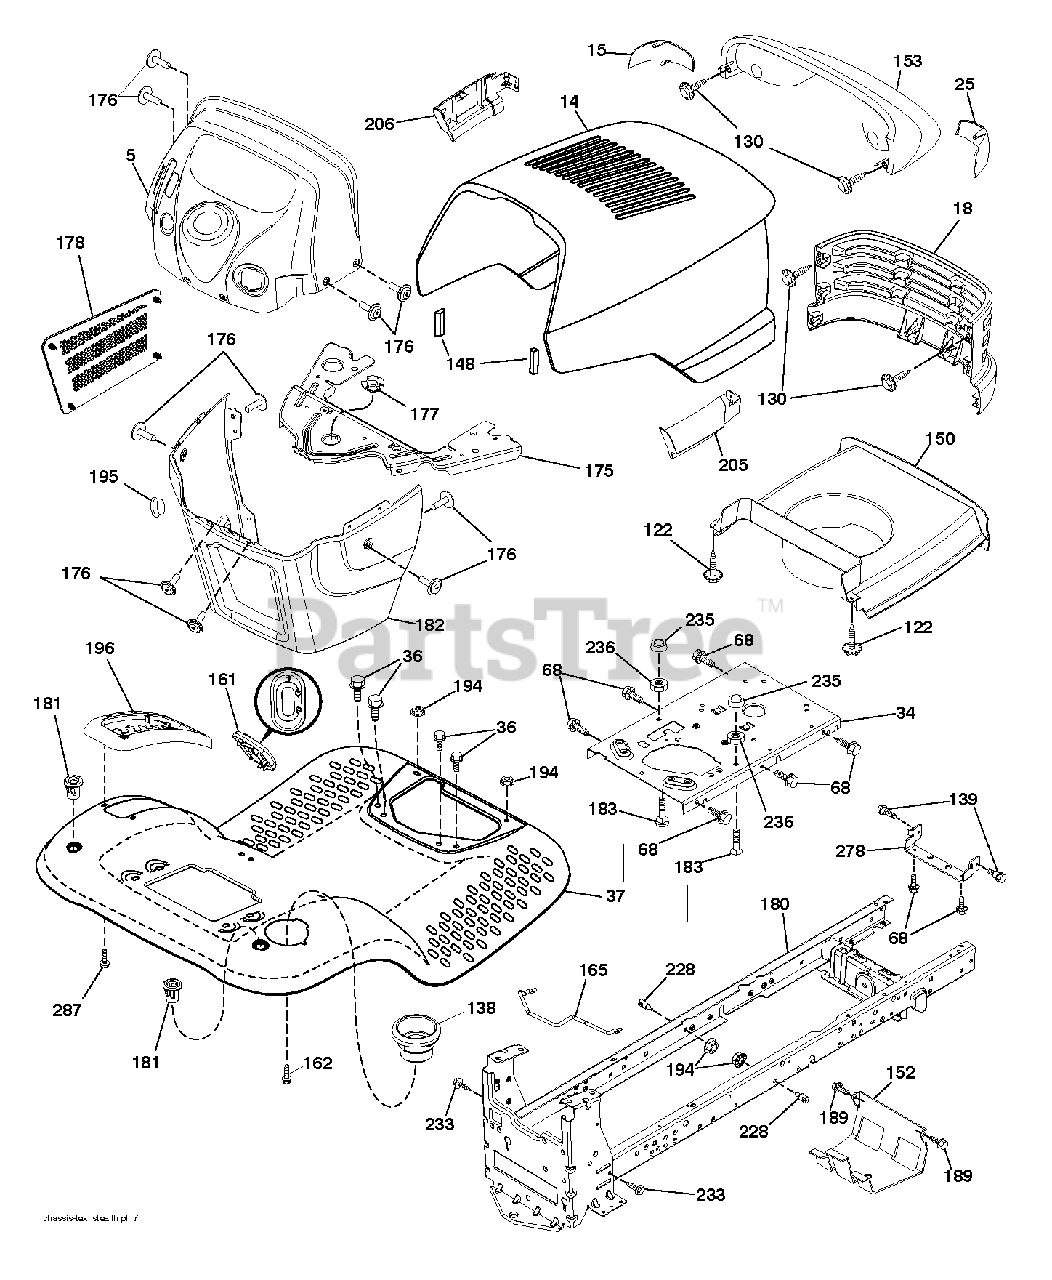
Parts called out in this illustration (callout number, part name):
5	DASH.UPR.STEALTH
15	LENS LH
25	LENS RH
34	PLATE.ENGINE.WELDED.CH
37	FENDER.TLT.W/CPH.W/FW.666
68	SCREW LT
130	SCREW.#10 X 0.750.BOS THREAD
138	CUPHOLDER
148	EXTRUSION BUMPER
150	DUCT HEAT HOOD
152	SHIELD BROWNING
161	WINDOW.FUEL.LT.TEX.428
162	SCREW,HEX
165	SUPPORT.TANK.REAR.W/TE
175	CROSSMEMBER.
176	SCREW.#10-24X5/8.RN.QU
177	BUSHING.STEERING.YT/GT
178	CARGO.ASM.NET.DASH.LOWER
180	CHASSIS
181	FEND/FTRST.PCH.CPH.NFW
182	DASH.LOWER.
183	BOLT.5/16-18X1-1/4 FULL THD
189	SCREW
194	NUT LOCK HEX FLANGE 5/16-18
195	PLUG.HOLE.DASH.LOWER.1
196	CONSOLE ASM. DECK LIFT
205	SKIRT.GRILLE.STEALTH.RH
206	SKIRT.GRILLE.STEALTH.LH
228	STUD.FASTNER.W/D.ANTI-
233	BOLT.SHOULDER
235	SPACER FENDER
236	JAM LOCK NUT
278	BRKT.HOOD/MUFF.STEALTH
